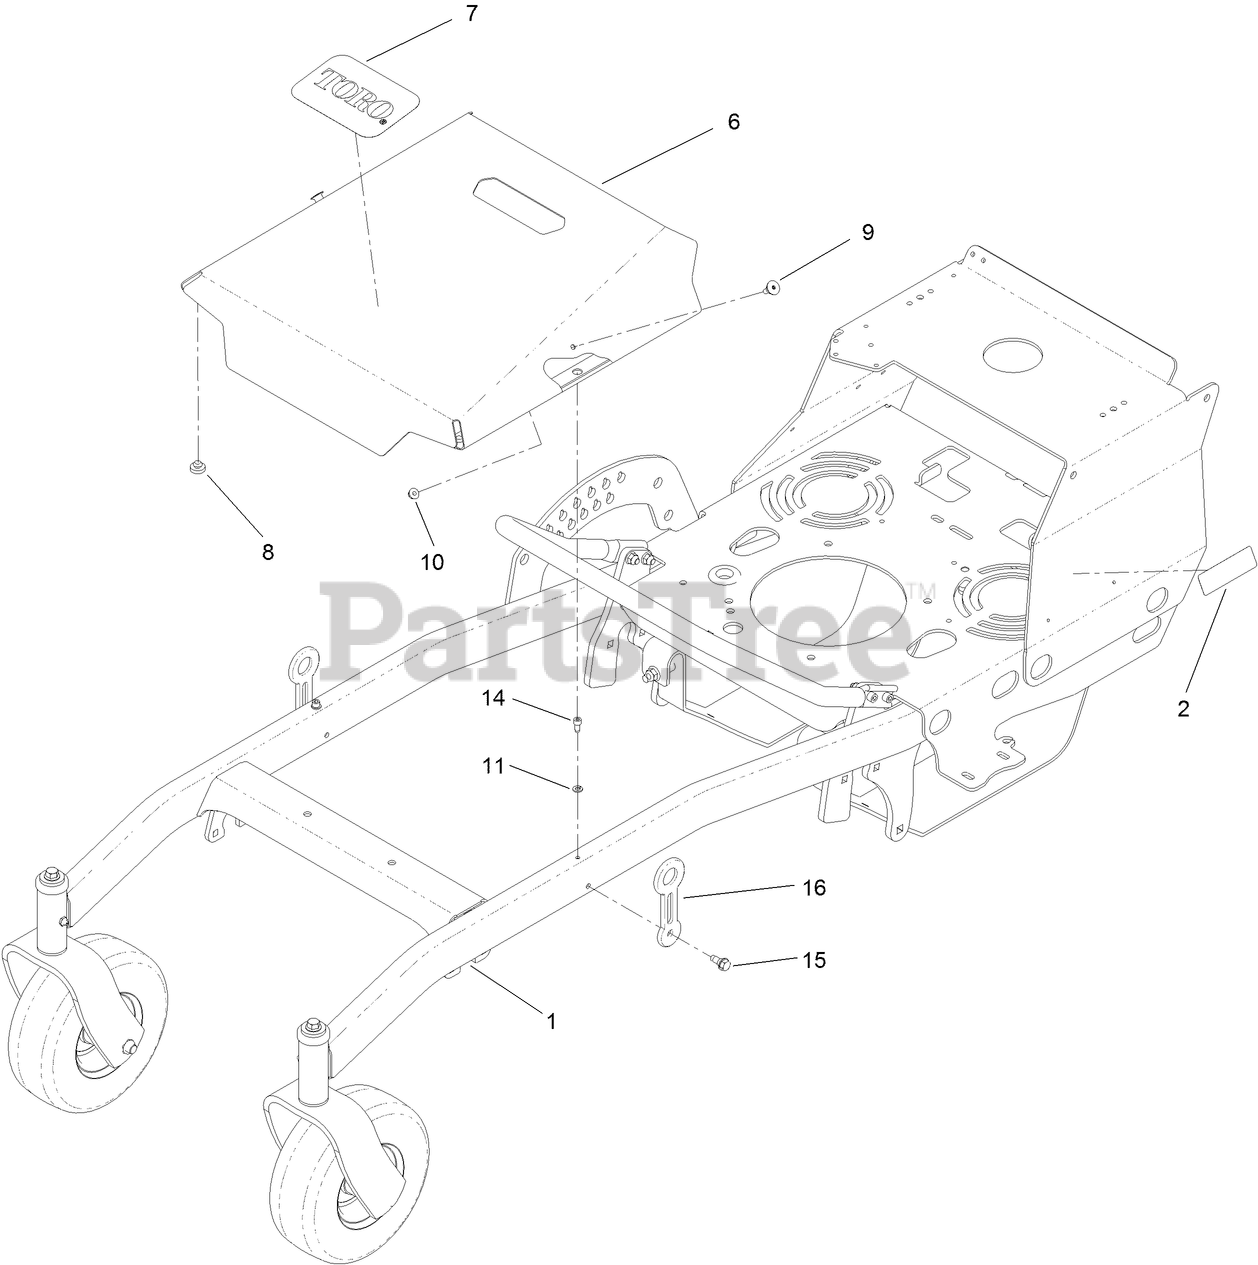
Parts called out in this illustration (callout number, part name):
1	FRAME ASSEMBLY
2	DECAL-EMISSIONS, EPA 2020
6	COVER-DECK
7	DECAL
8	BUMPER
10	NUT-HF
11	WASHER-LOCK
14	SCREW-HSH, THREAD FORMING
15	SCREW-SHOULDER
16	LATCH-RUBBER
